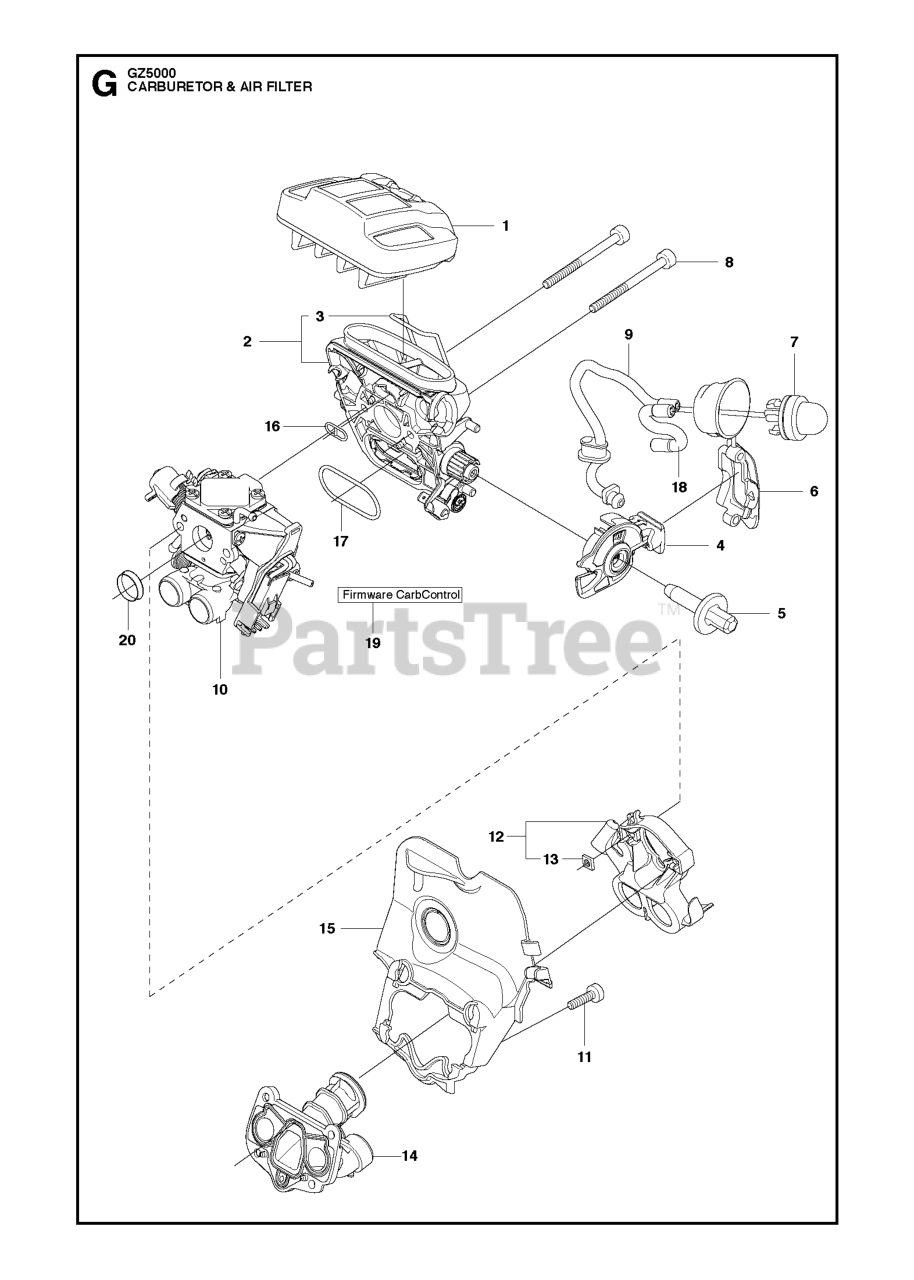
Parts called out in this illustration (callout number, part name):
1	AIR FILTER
1	AIR FILTER ASSY
2	FILTER HOLDER ASSY
4	CHOKE CONTROL ASSY CHOKE/STOP
7	AIR PURGE BUBBLE
8	SCREW ITXSCM
9	VENTILATING HOSE,KIT
9	FUEL HOSE
10	CARBURETTOR KIT
11	SCREW ITXSCM M4X15 T27 12.9 T
13	NUT SQUARE
14	INLET PIPE ASSY
15	INTERMEDIATE WALL
18	FUEL HOSE
19	NA
20	SUPPORT SLEEVE
